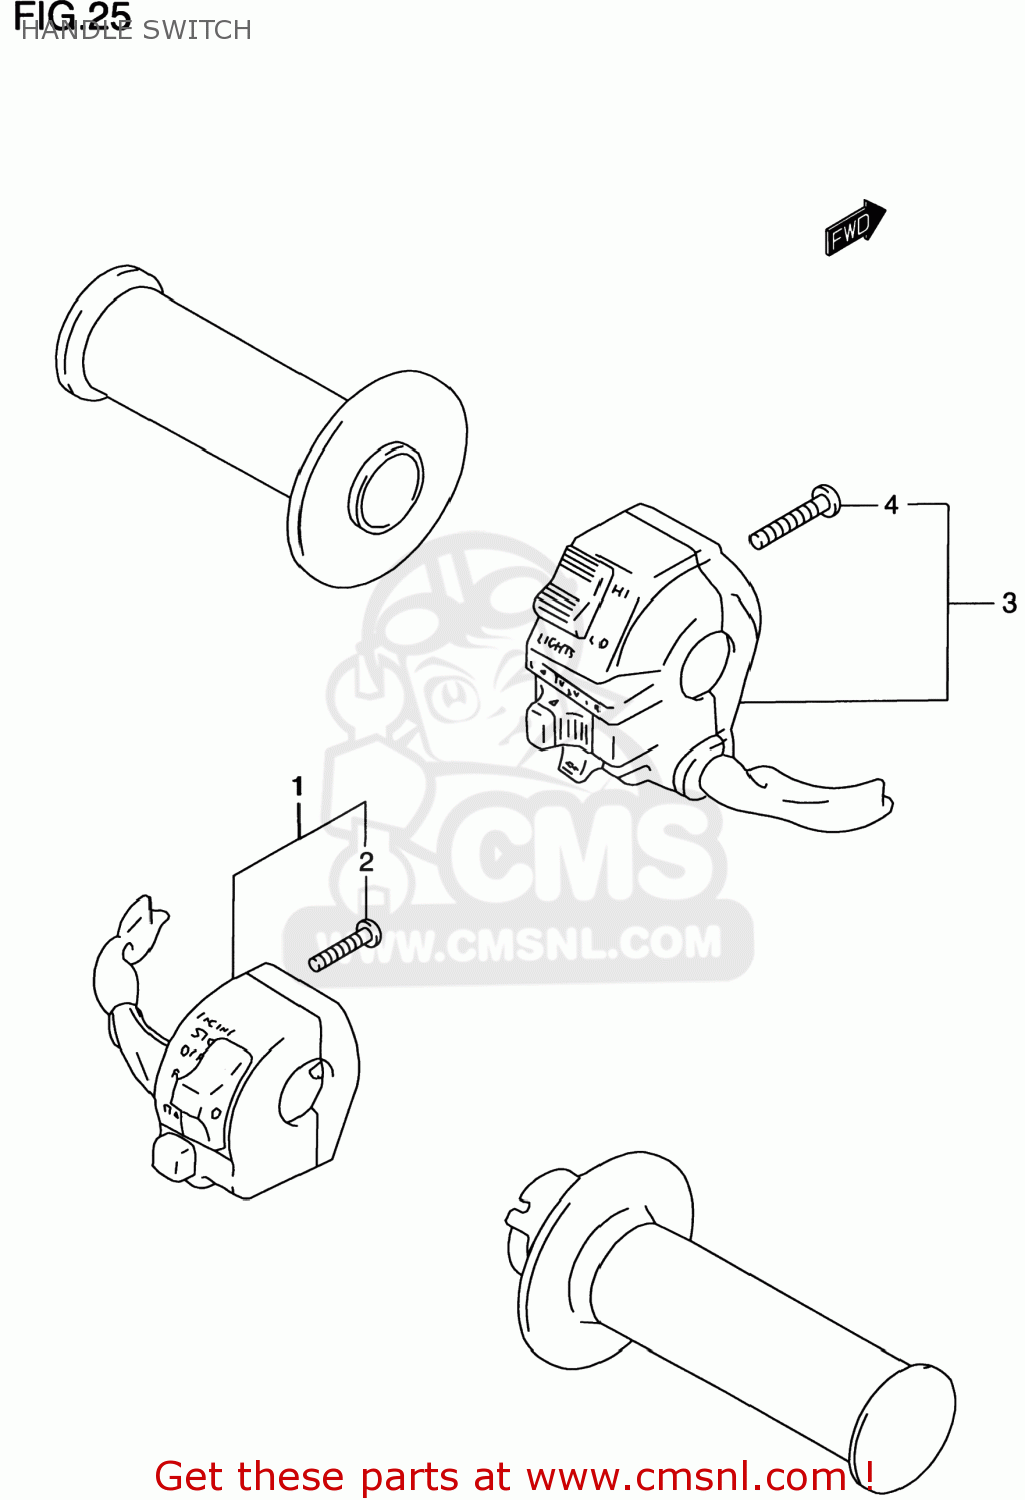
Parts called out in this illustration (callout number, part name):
1	SWITCH ASSY,HANDLE,R
2	SCREW
3	SWITCH ASSEMBLY,HANDLE,LEFT
4	SCREW
